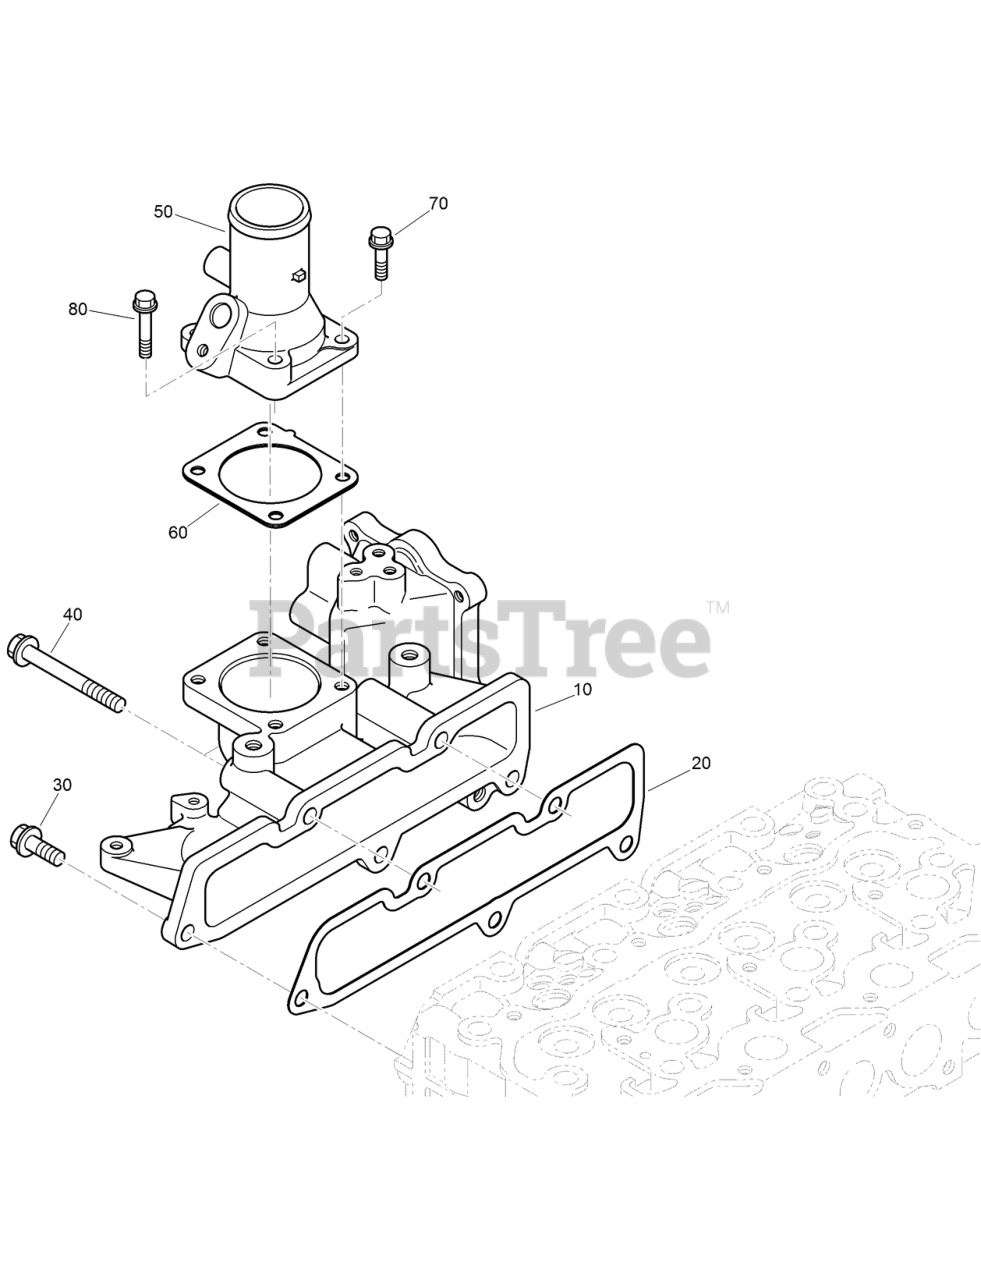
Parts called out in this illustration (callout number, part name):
10	MANIFOLD-INLET
20	GASKET-MANIFOLD, INLET
30	BOLT-FLANGE
40	BOLT-FLANGE
50	FLANGE-INLET
60	GASKET-FLANGE, INLET
70	BOLT-FLANGE
80	BOLT-FLANGE
